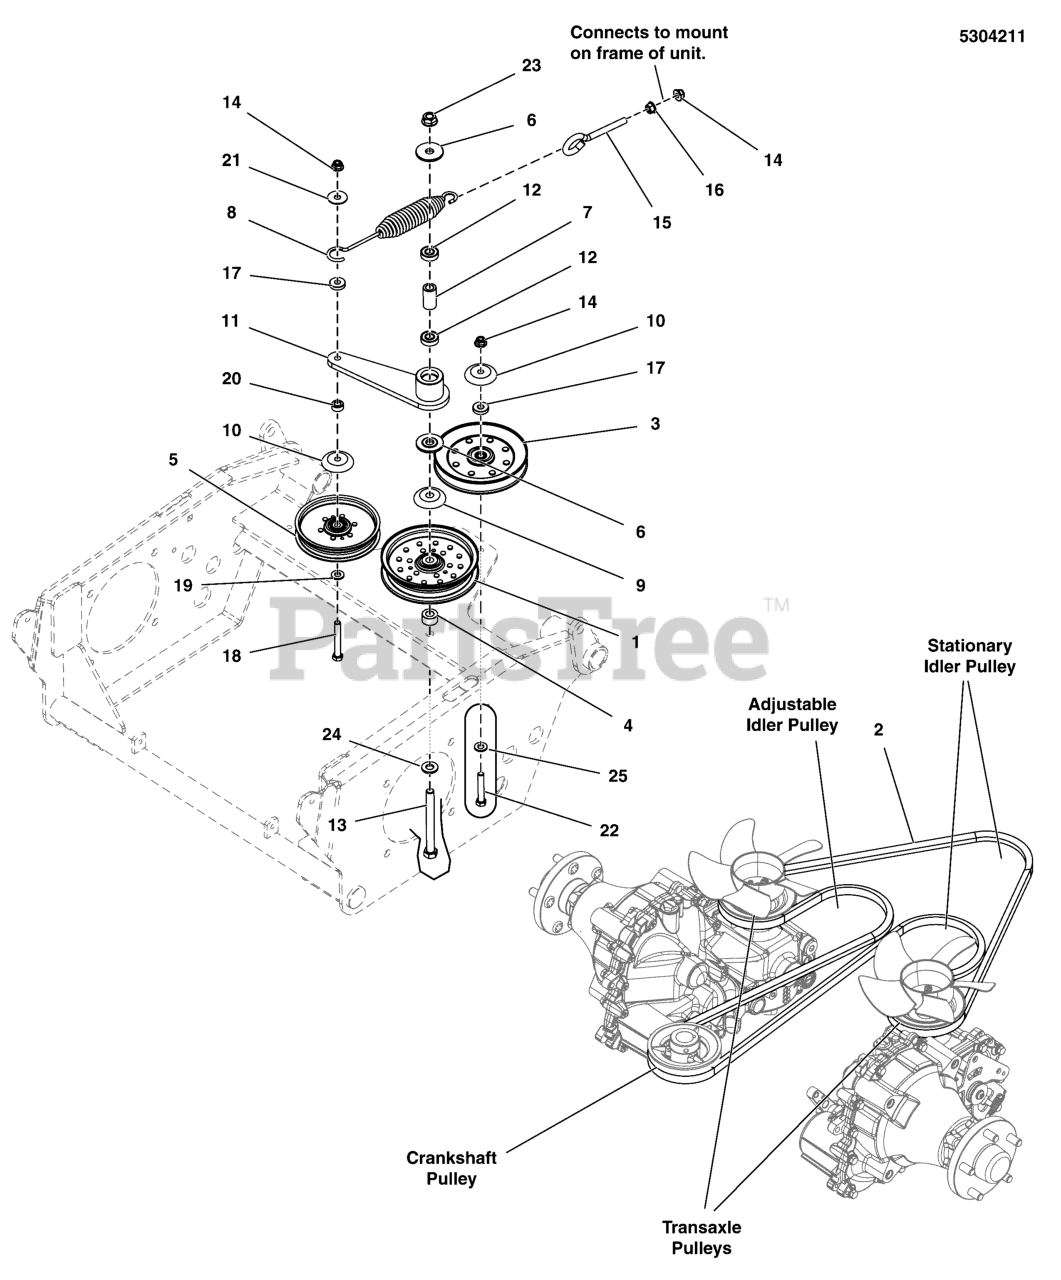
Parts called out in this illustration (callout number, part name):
1	PULLEY, IDLER, 5" OD, 1"FACE, 5.75 FL
2	BELT, B-SEC, 143.75"EL, ARAMID, WRPD
3	PULLEY-IDLER-V, 5.83OB, .38ID, .94W, STL
4	SPACER, .52 X 1.00 X .56, PM, CZ
5	PULLEY, C-SEC, V-IDLER, 6.25"ODX3/8ID
6	SPACER, IDLER ARM, 1/2, PM
7	SPACER, .52 X .84 X 1.53, PM
8	SPRING-EXT, 1.25OD X 9.3LG X .142WR, BLK
9	SHIELD, PULLEY BEARING, CZ
10	SHIELD, BEARING PULLEY, 3/8ID, CZ
11	WELD, IDLER ARM, PUMP DRIVE, 6.38 - BLK
12	BEARING, BALL, AXLE
13	BOLT-1/2-13 X 5 GD5 CZ
14	NUT, 3/8-16 HEX NYLOCK FLANGE
15	EYE BOLT, 3/8-16 X 8, 3THRD, 1EYE, CZ
16	NUT, 3/8-16 HEX SERRATED FLANGE
17	SPACER, .39 X 1.00 X .25, PM, CZ
18	BOLT, 3/8-16 X 2-3/4" GD5 CZ
19	WASHER, 3/8 GD.9 FLAT
20	SPACER, .39 X 1.00 X .50, PM, CZ
21	WASHER-3/8 FENDER
22	BOLT, 3/8-16 X 2-1/4" GD5 CZ
23	NUT, Hex Flange, Nylock, 1/2-13
24	WASHER, 1/2 SAE
25	WASHER, 3/8 SAE
